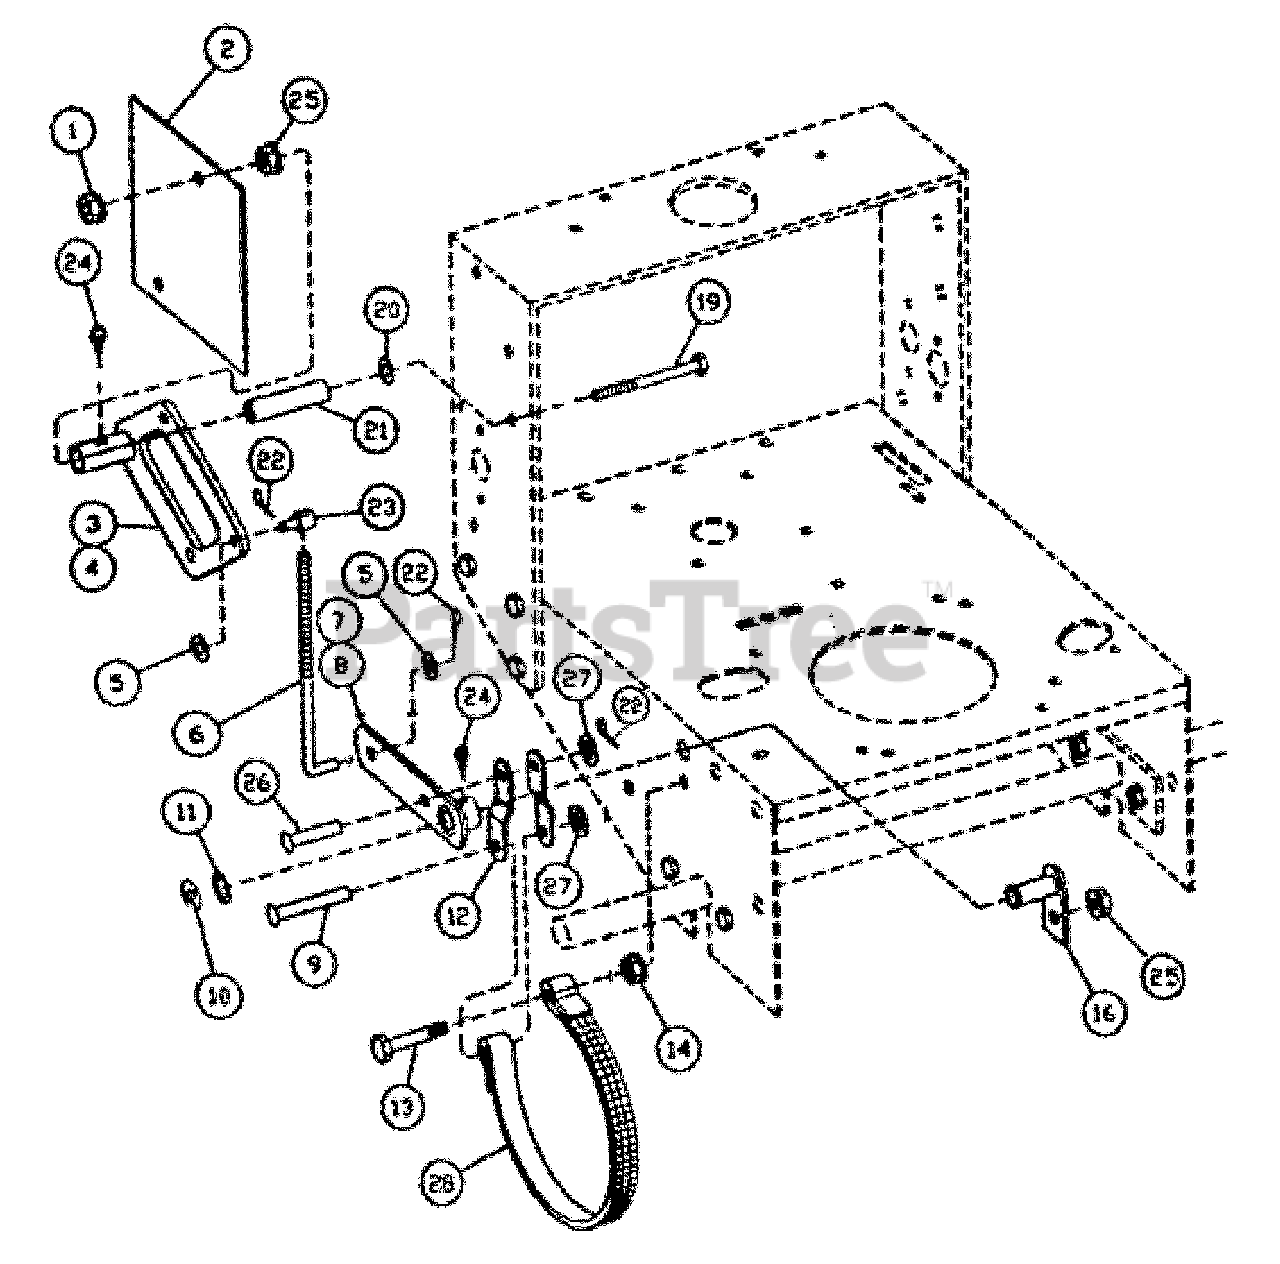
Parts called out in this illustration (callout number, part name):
1	NUT, 200-001 M10
2	100-005 FENDER
3	100-034 IDLER ARM RH
4	100-035 IDLER ARM LH
5	5/16STD FLAT WASHER.
6	100-036 BRAKE ROD
7	100-037 BRAKE LEVER RH
8	100-038 BRAKE LEVER LH
9	100-039 FLAT HEAD RIVET
10	200-047 SNAP-RING -10 PACK
11	100-120 PLAIN WASHER
12	100-040 BRAKE LINK
13	200-032 HEX BOLT M10`50
14	200-016 NUT FLANGE M10
16	100-041 BRAKE LVR MT.
19	200-008 HEX.BOLT M10`110
20	100-003 WASHER
21	100-004 PIVOT TUBE
22	200-014 COTTER PIN 2`20
23	100-042 SWIVEL BRAKE ROD
24	GREASE FTG (10 PACK) 200-026
25	200-006 NYLON NUT M10
26	100-043 FLAT HEAD RIVET
27	200-033 PLAIN WASHER 10
28	100-044 BRAKE ASM BAND
